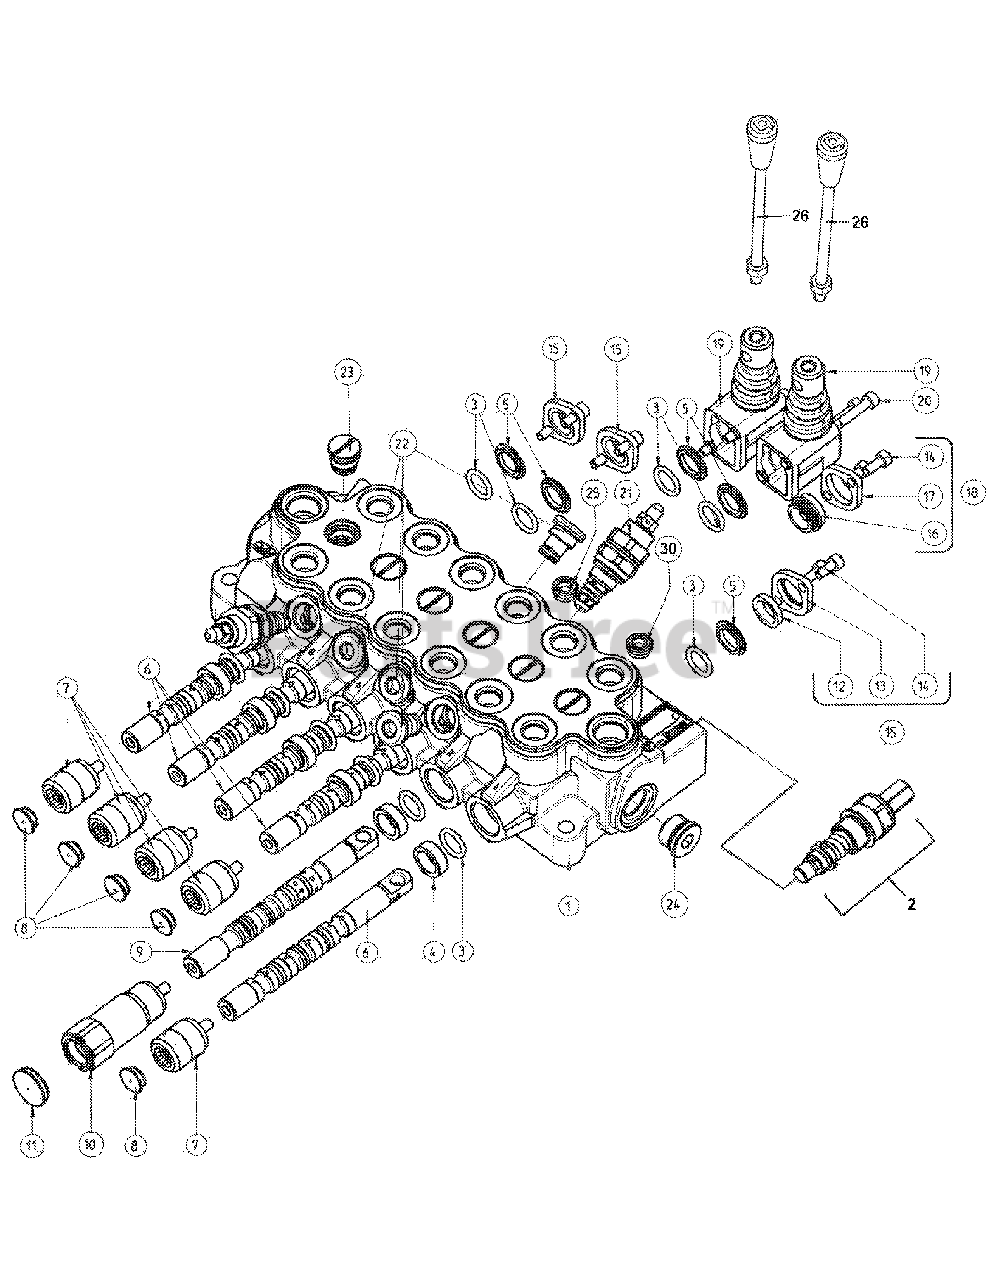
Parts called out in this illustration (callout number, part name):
1	Valve Casting Body
2	Main Relief Cartridge Components - 2250 psi
3	Spool Seal
4	Spacer
5	Metal Washer
7	Positioner
8	Plug for Positioner
9	Boom Spool for Non-Detented "Float"
10	Boom Positioner with Non-Detented "Float"
12	Spool Wiper
13	Retaining Plate
14	Socket Screw, M5 x 0.8 x 12 DIN 912
15	Wiper Retaining Plate
16	Spacer with two O-Rings
17	Retaining Plate - Boom
18	Wiper Retaining Plate and Hardware
19	Stabilizer Lever Box Assembly
20	Socket Screw, M5 x 0.8 x 45 DIN 912
21	Work Port Relief Valve - 2175 psi
22	Work Port Plug
23	Load Check Valve
24	Plug, 3/4-16 UNF SAE 8
25	.046 inch Orifice Assembly
26	Stabilizer Handle Assembly
27	Control Valve Seal Service Kit
28	Wiper Retaining Plate Kit
29	Complete Valve Assembly
30	Orifice Assembly, .076 inch
